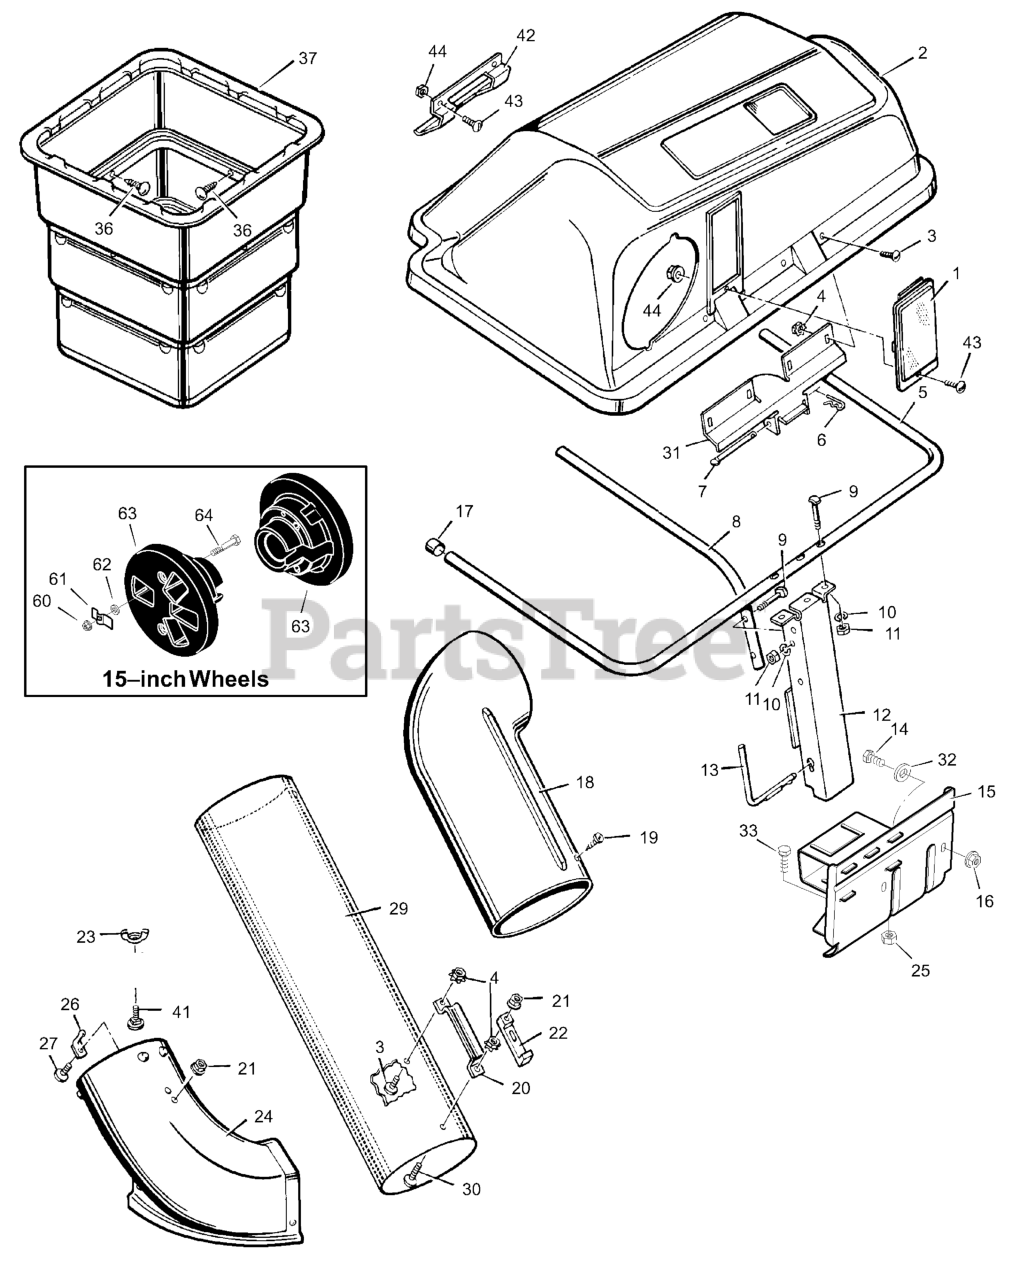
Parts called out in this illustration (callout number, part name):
4	Locknut
6	Pin, Hair
7	Pin, Hinge
8	Tube, Center
9	Bolt, Special
10	Lockwasher
11	Nut, Hex
12	Channel Assembly
13	Pin, Channel
14	Bolt, Hex
15	Mount Assembly, Bagger
16	Nut, Hex
17	Cap, End
20	HANDLE, Connect Tube
21	Locknut, Flange
22	Latch, Rubber
23	Wingnut
24	Tube, Extension
25	Hex Nut
26	Pin, Latch
27	Bolt, Carriage
29	Tube, Connector
31	Hinge, Cover
33	Bolt, Hex
36	Fastener, Plastic
37	Containers (Quantity 2)
41	Bolt, Carriage
42	Handle, Plastic
44	Nut, Hex
60	Nut, Flange
61	Clip, Wheel
62	Retainer
63	Weight, Wheel
